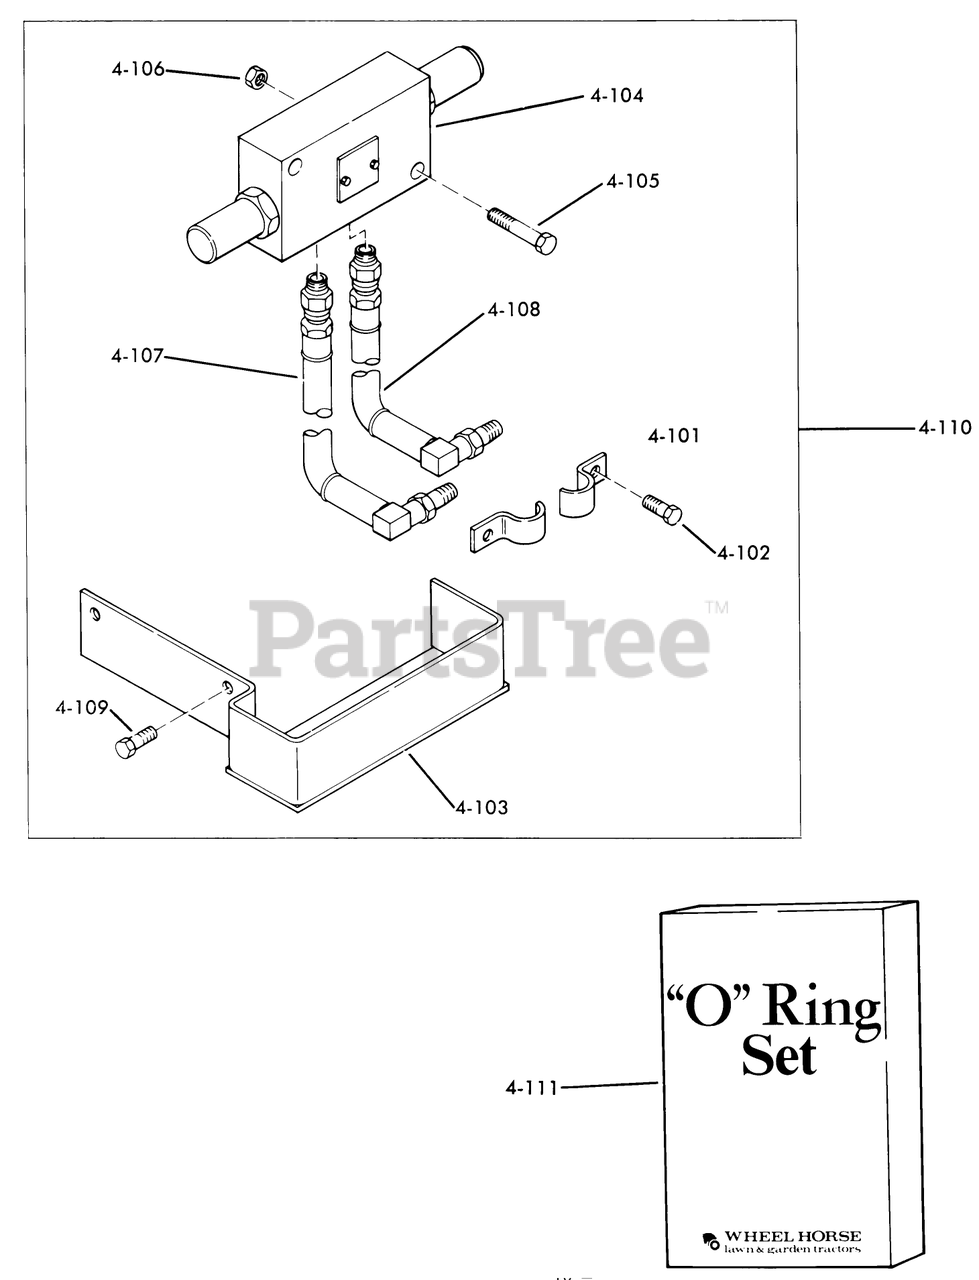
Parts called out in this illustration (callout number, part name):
4-101	BRACKET
4-102	Bolt
4-103	Capscrew
4-104	Relief Valve
4-105	Bolt
4-106	NUT
4-107	HOSE-HYDRAULIC FRONT
4-108	ASSY-HYD HOSE FRONT
4-109	BOLT
4-110	Relief Valve Kit-S.A.
4-111	O-Ring Kit-S.A. Incs 15, 16, 17 & 21
